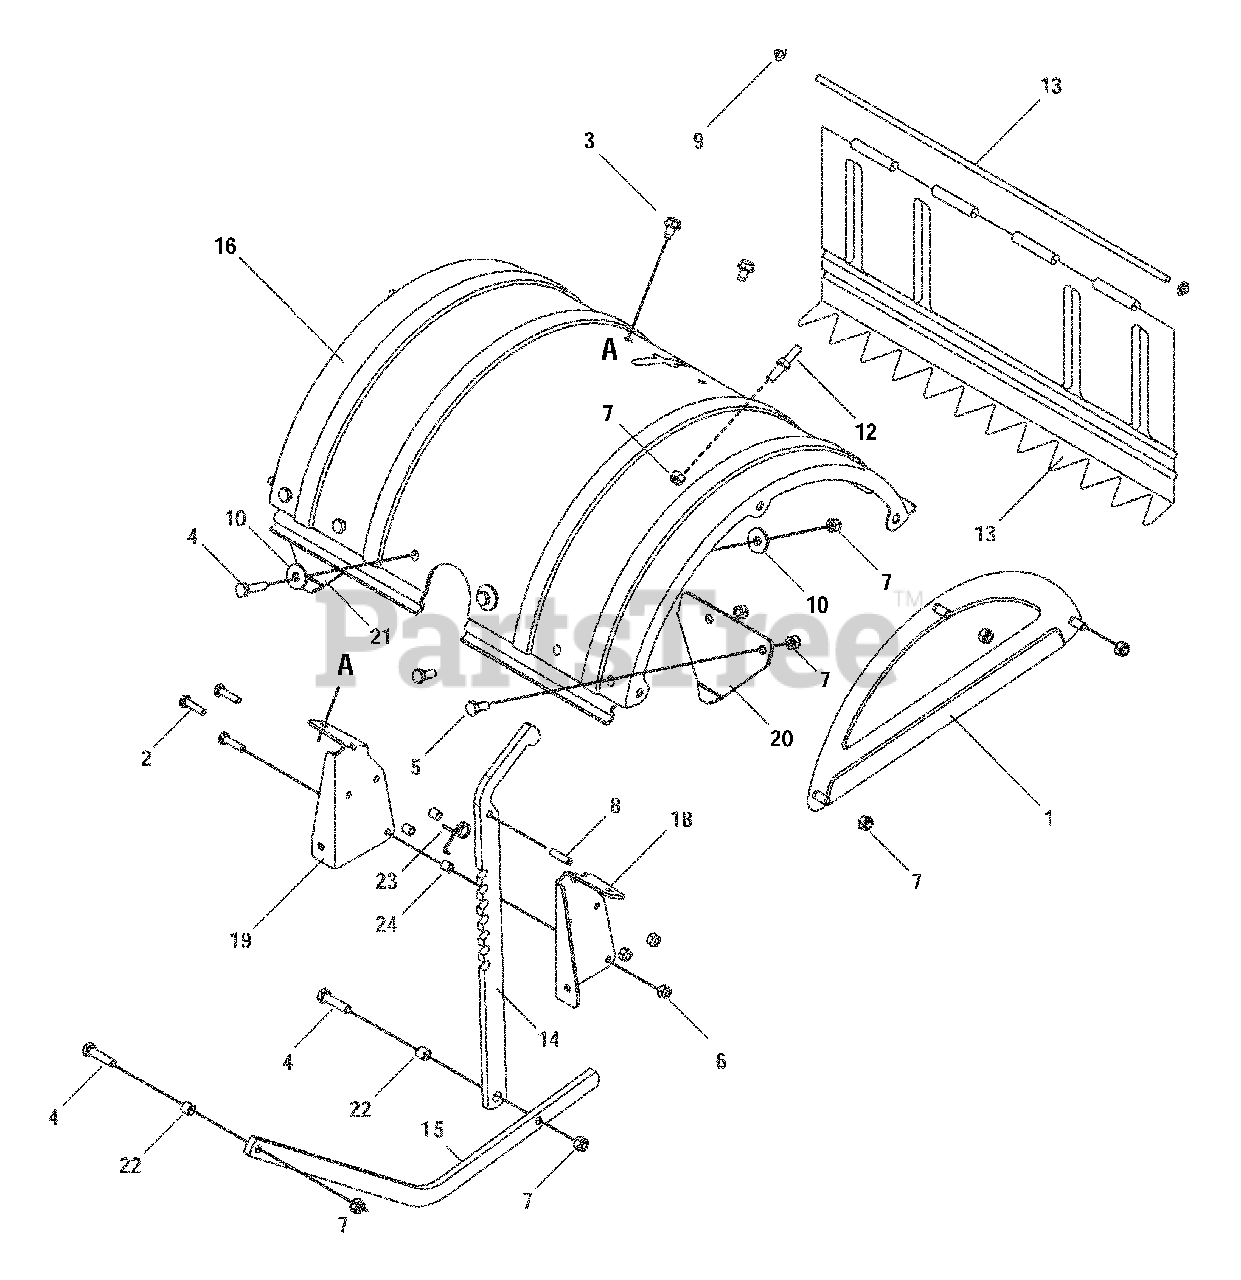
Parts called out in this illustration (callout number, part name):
2	Hex Screw, 1/4-20, 1.00, Gr5
3	Screw, Self-tapping, 5/16-18, 0.625,
4	Hex Screw, 5/16-18, 1.25, Gr5
5	Hex Screw, 5/16-18,.75, Gr5
6	Nut, Hex Lock, 1/4-20, Gr8, Nylon
7	Nut, Hex Lock, 5/16-18, Gr5, Nylon
8	Pin, Spring, 1/4 Dia x 1.00 Lg
9	Nut, Speed, Cap 1/4 Rod
10	Washer, Flat,.345 x 1.00 x.100
11	Screw, Hex, 5/16-18 x.75
12	Rod, Tiller Flap
14	Bar, Depth
15	Bar, Drag, Depth
16	Shield, Tine
17	Bracket, Shield, Tine
18	Bracket, Mounting, Bar, Depth, LH
19	Bracket, Mounting, Bar, Depth, RH
20	Bracket, Deflector, LH
21	Bracket, Deflector, RH
22	Bush,.438 x.323 x.400
23	Spring Torsion
24	Spacer,.350 x.268 x.375
